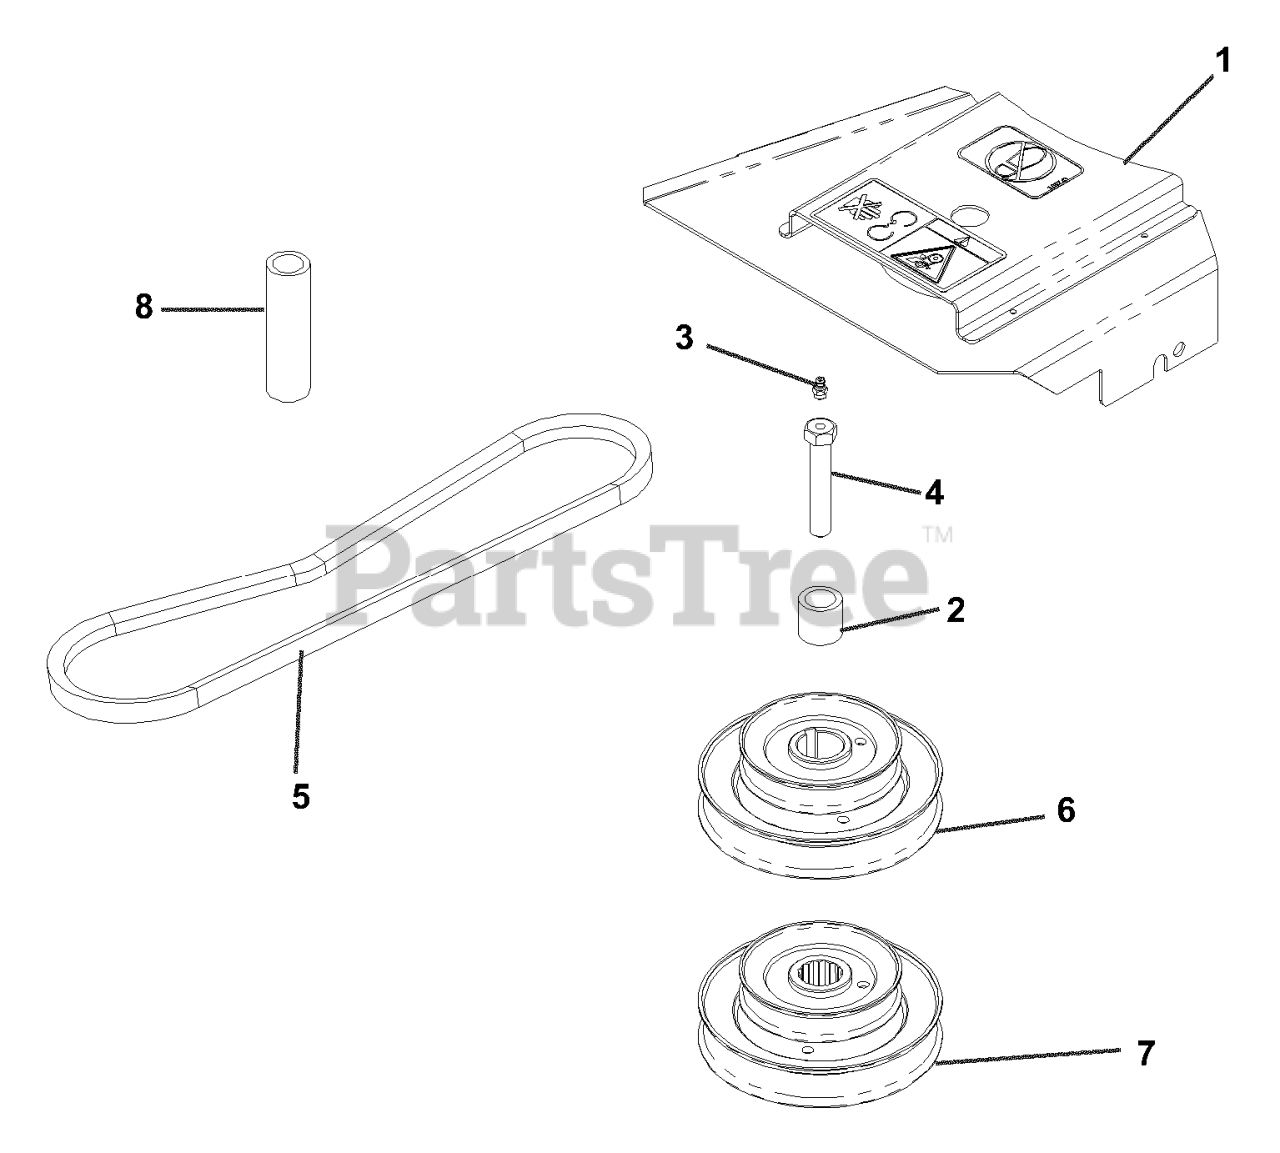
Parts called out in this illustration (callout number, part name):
1	SHEILD WELDMENT 42
1	SHIELD WELDMENT 48"
1	SHIELD WELDMENT 52"
1	SHIELD WELDMENT 61
2	SPACER
3	ZERK
4	DRILLED BOLT 7/16-20 X 2 1/2"
5	V-BELT 42" SPINDLE DRIVE
5	V-BELT 48" SPINDLE DRIVE
5	V-BELT PUMP DRIVE
5	V-BELT 61" SPINDLE DRIVE
6	STACKED SHEAVE 42-48
6	PULLEY 52"
6	STACKED SHEAVE
7	61 DBL HEX HEAD STACKED PULLEY
8	STOP
